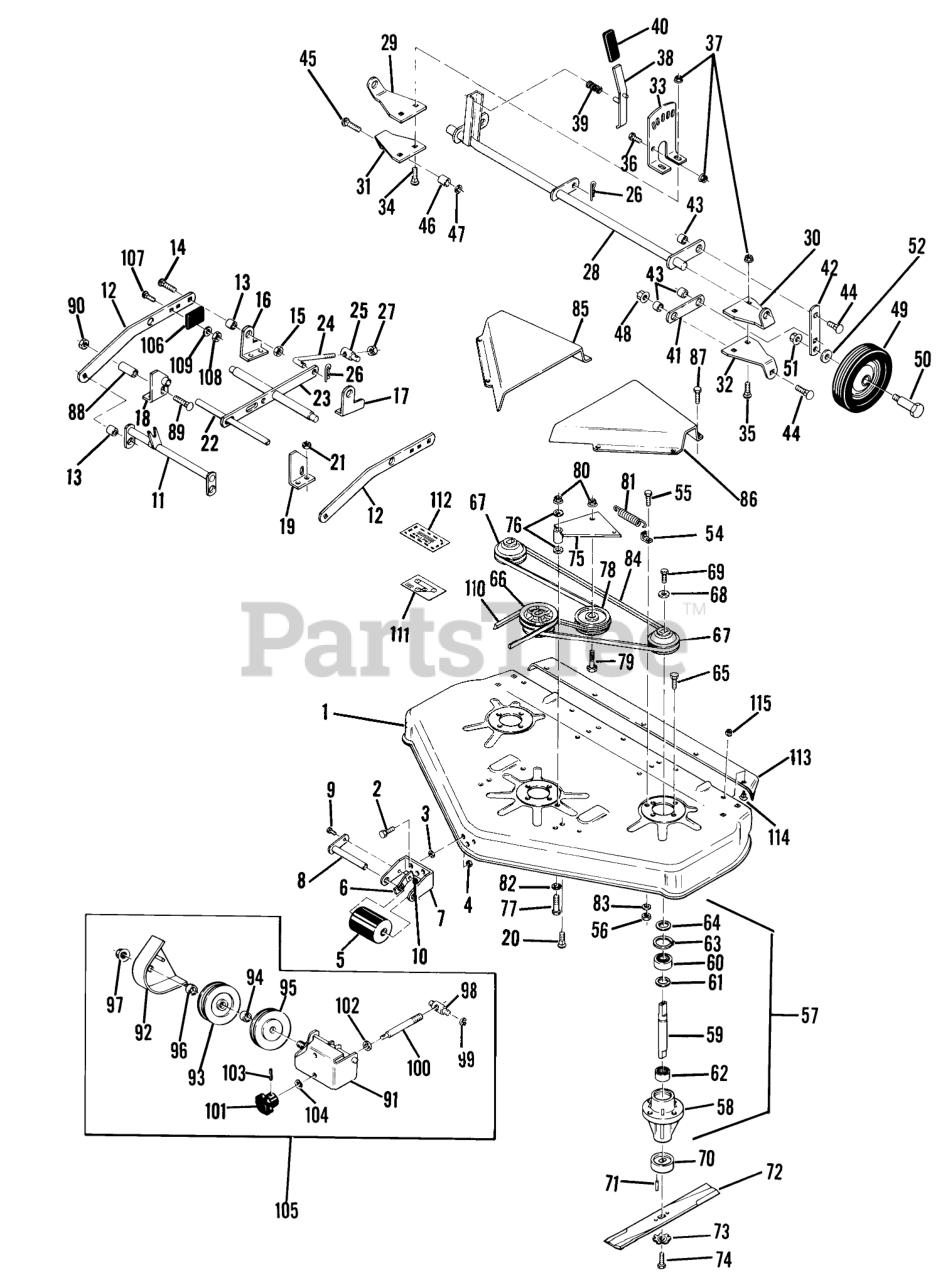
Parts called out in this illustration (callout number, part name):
1	Mower Deck Assembly
2	Bolt
3	Collar
4	Nut
5	Roller
6	SPRING ROLLER STOP
7	Bracket
8	Roller Shaft
9	HHCS
10	Nut
11	Hitch
12	Bar Draft
13	SPACER
14	Bolt
15	LOCKNUT-FLANGE
16	R.H. Rear Bracket
17	L.H. Rear Bracket
18	Front Bracket RH
19	Front Bracket LH
20	Bolt-Carriage
21	Nut
22	Front Shaft
23	Leveler
24	ROD-LEVEL ADJUST
25	TRUNNION-LIFT
26	Hairpin
27	NUT
28	Gage Wheel Support
29	Bracket-R.H. Upper
30	Bracket-L.H. Upper
31	Bracket-Lower R.H.
32	Bracket-L.H. Lower
33	Quadrant
34	Bolt
35	Bolt
36	Bolt
37	LOCKNUT-FLANGE
38	Lever
39	SPRING-COMPRESSION
41	SUPPORT LINK R
42	WHEEL SUPPORT LINK
43	SPACER
44	Bolt
45	Bolt
46	Spacer
47	WASHER
48	LOCKNUT-FLANGE
49	Wheel
50	BOLT-SHOULDER
51	LOCKNUT-FLANGE
52	WASHER
54	CLIP - SPRING
55	Bolt
56	Nut
57	Spindle Assy.
58	HOUSING SPINDLE
59	SHAFT SPINDLE
60	BEARING
61	Snap Ring
62	NEEDLE BEARING
63	INT SNAP RING
64	WASHER
65	Bolt
66	Center Pulley
67	End Pulley
68	WASHER
69	Bolt
70	Cup-Spindle
71	SPIROL ROLL PIN
72	Mower Blade
73	WASHER
74	Bolt
75	Idler Arm Assembly
76	SPACER
77	Bolt
78	Idler Pulley
79	HEX HD CAP SCREW
80	LOCKNUT-FLANGE
81	SPRING IDLER
82	WASHER
83	WASHER
84	V BELT
85	R.H. Belt Cover
86	L.H. Belt Cover
87	Bolt
88	SPACER-BEARING
89	CARRIAGE BOLT -4
90	Nut
91	Front Support
92	Belt Cover
93	PULLEY-FLAT IDLER
94	SPACER
95	Pulley-V
96	SPACER-OUTER
97	Nut 3/4-16 MF
98	TRUNNION-DOUBLE
99	RING-RETAINING
100	ROD ADJ
101	KNOB-ADJUSTMENT
102	Washer
103	PIN-ROLL
104	Washer
105	ASM-SUPPORT,IDLER
106	BUMPER
107	Bolt-Carriage
108	Nut
109	Collar
110	V-BELT
111	Decal Belt Diagram
112	Caution Decal
113	Grooved Pin 5X28MM
114	CARRIAGE BOLT -4
115	Nut
